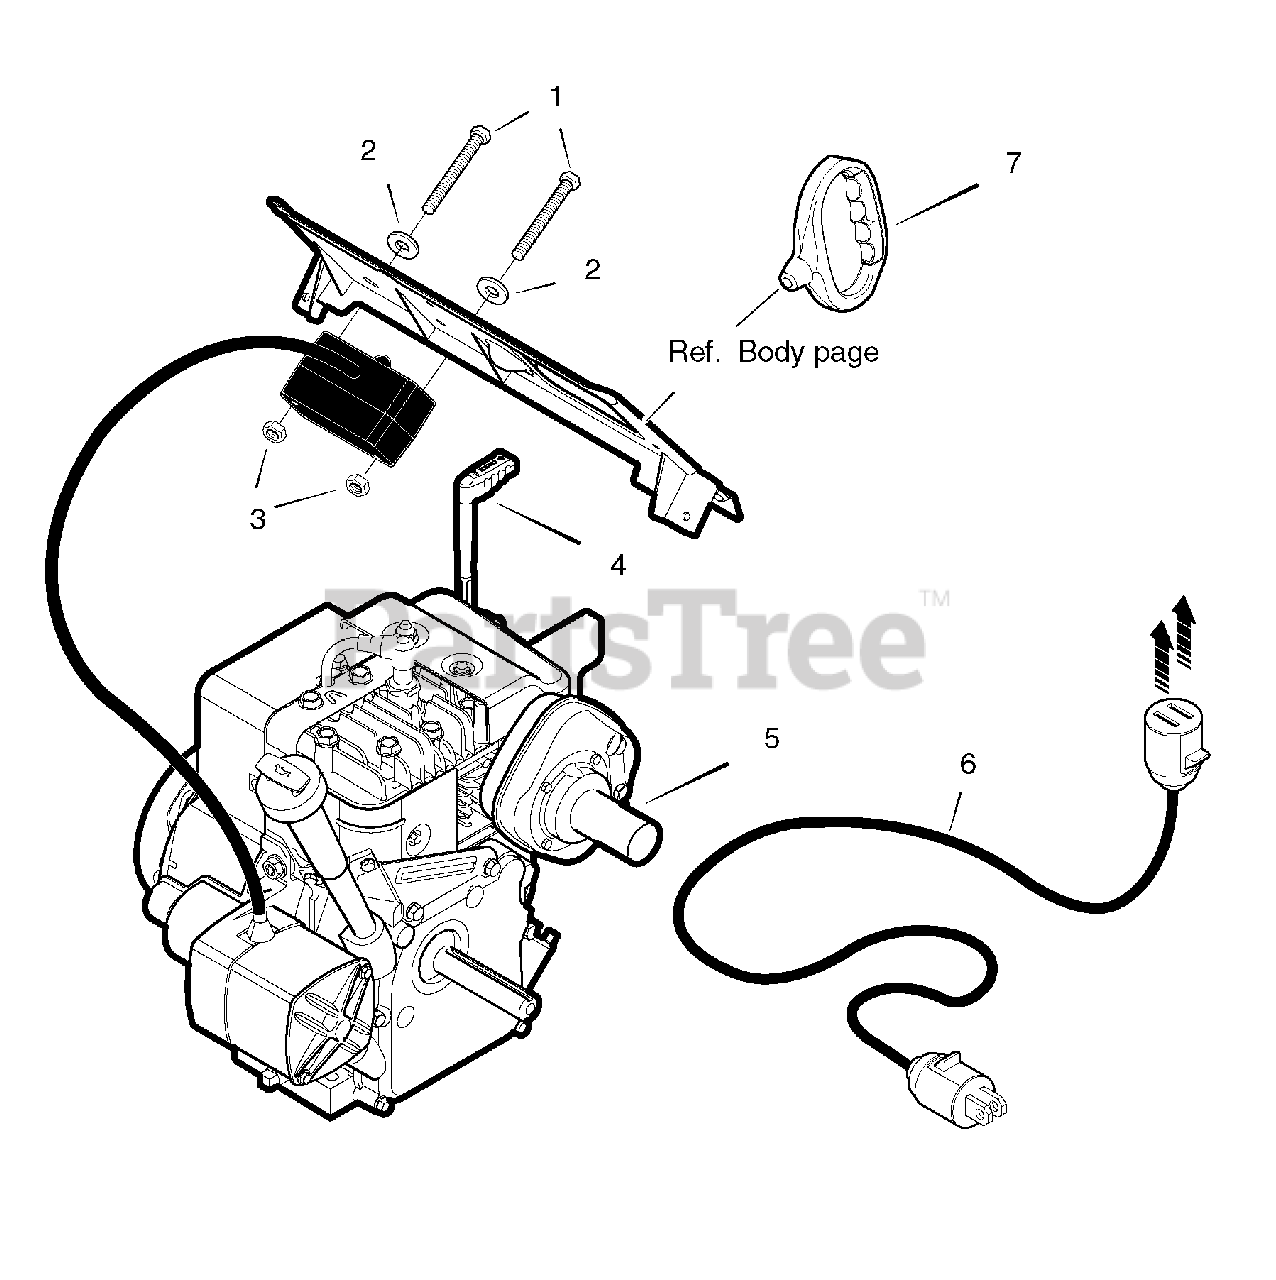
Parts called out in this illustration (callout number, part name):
1	CAPSCREW, # 8-32 x 3
2	WASHER, Flat
4	* LEVER, Choke
5-1	* Muffler
5-2	* GASKET, Muffler
5-3	* CAPSCREW, Torx Socket Head, Muffler
5-4	WASHER, Split Lock
5-5	NUT, Hex, 5/16 - 18
5-6	BOLT, Hex, 5/16 - 18
6	CORD, Extension
7	GRIP, Starter Rope
